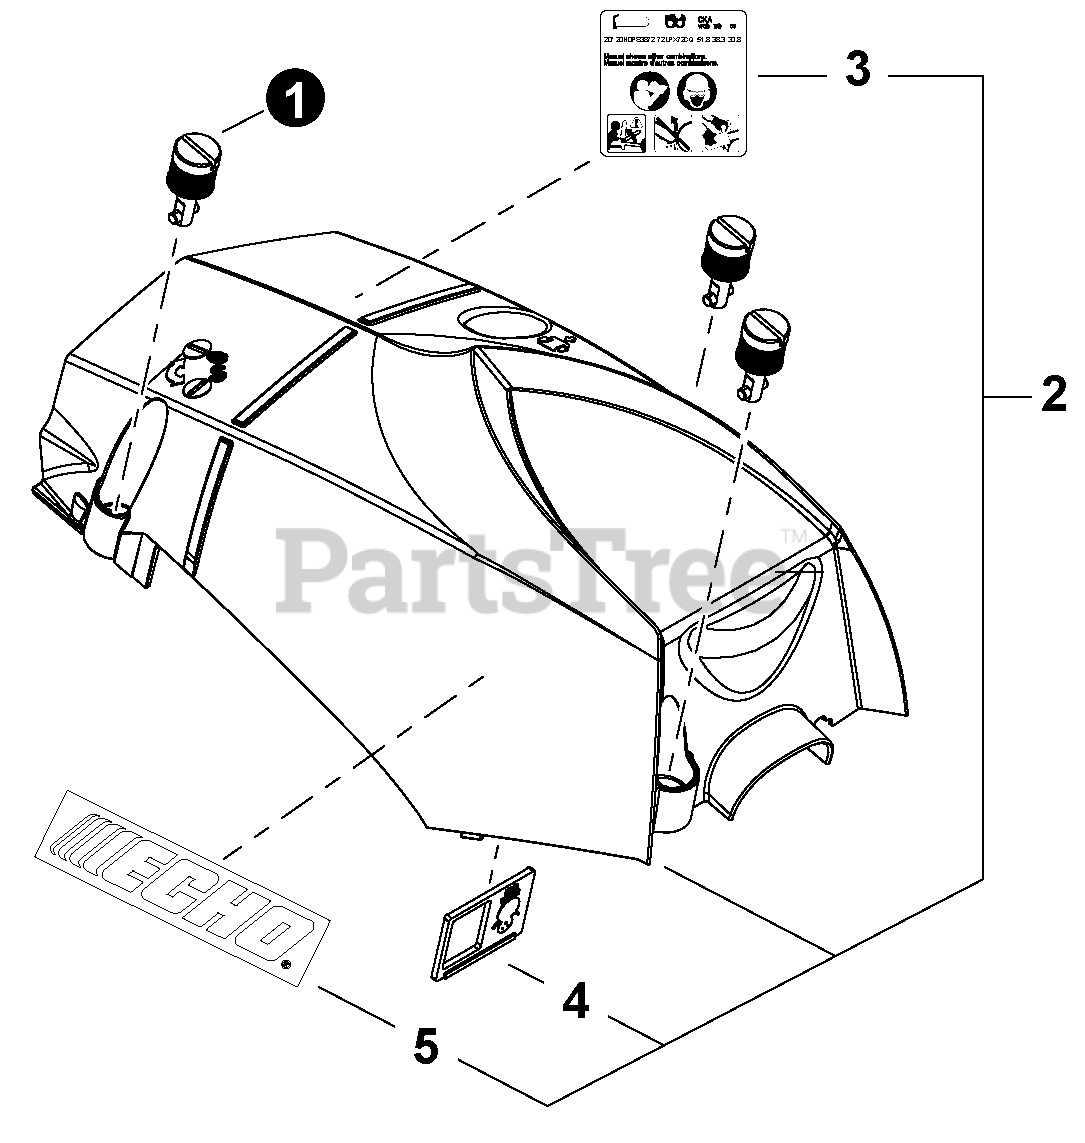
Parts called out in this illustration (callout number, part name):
1	PIN, SNAP
2	COVER ASSY, ENGINE
3	LABEL - CAUTION - ISO
4	PLATE, SHUTTER
5	LABEL - ECHO
